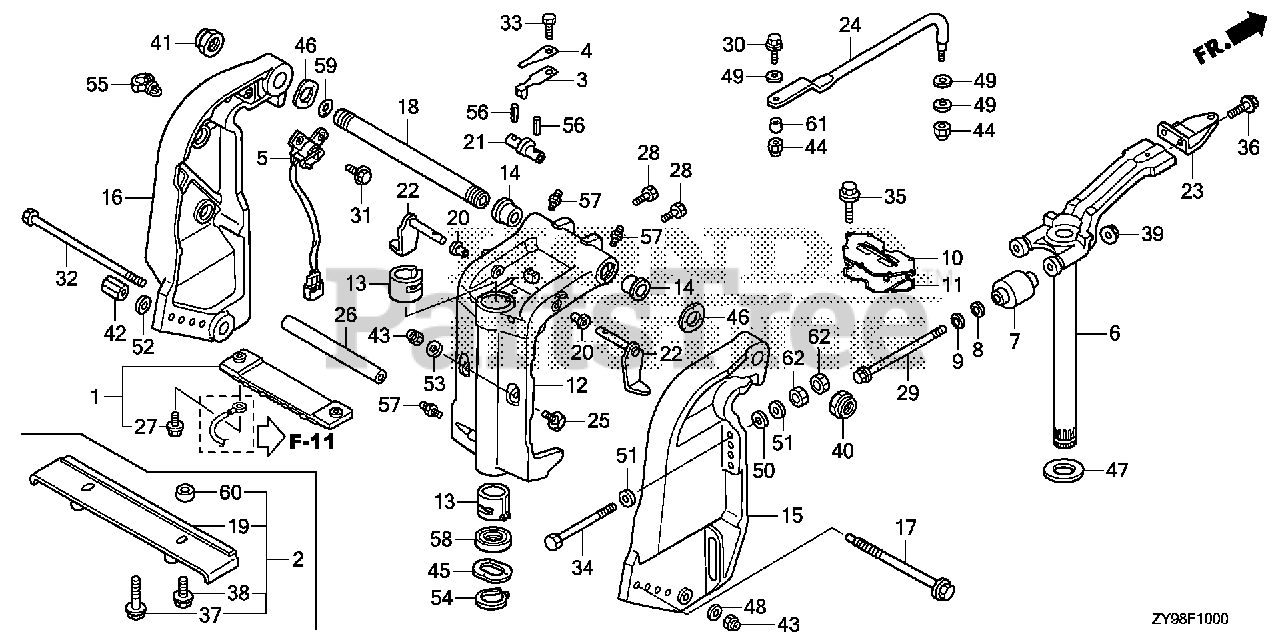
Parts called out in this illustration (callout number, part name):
1	METAL KIT, ANODE
2	PLATE KIT, SPLASH
3	SPRING, CLICK
4	SPRING, CLICK ASSIST
5	SENSOR ASSY., TRIM ANGLE
6	FRAME, MOUNTING
7	MOUNT, RUBBER (UPPER)
8	RUBBER, MOUNT STOPPER (UPPER)
9	STOPPER, MOUNT (UPPER)
10	COVER, MOUNT (UPPER)
11	SEAL, MOUNT COVER (UPPER)
12	CASE, SWIVEL *NHB14M* (AQUA MARINE SILVER METALLIC)
13	LINER, SWIVEL CASE
14	BUSH, SWIVEL CASE
15	BRACKET, R. STERN *NHB14M* (AQUA MARINE SILVER METALLIC)
16	BRACKET, L. STERN *NHB14M* (AQUA MARINE SILVER METALLIC)
17	ROD, ADJUSTING
18	SHAFT, TILTING
19	PLATE, SPLASH
20	BUSH, TILT ARM
21	BRACKET, TILTING
22	STOPPER, TILT
23	PLATE, STEERING
24	ROD, STEERING
25	RECEIVER, THRUST
26	COLLAR, CYLINDER (LOWER)
27	BOLT, FLANGE (6X23)
28	BOLT (1/4-28UNF)
29	BOLT, HEX. (12X186)
30	BOLT (3/8-24UNF)
31	BOLT, FLANGE (6X20)
32	BOLT, HEX. (10X235)
33	BOLT, HEX. (6X14)
34	BOLT, HEX. (12X119)
35	BOLT, FLANGE (8X25)
36	BOLT, FLANGE (10X25)
37	BOLT, FLANGE (6X25) (SUS-D)
38	BOLT, FLANGE (6X16) (SUS)
39	NUT, FLANGE (12MM)
40	NUT, SELF-LOCK (7/8-14UNF)
41	NUT, SELF-LOCK (25X2.0)
42	NUT, ADJUSTER ROD
43	NUT, FLANGE (10MM)
44	NUT, SELF-LOCK (3/8-24UNF)
45	WASHER, WAVE (40MM)
46	WASHER, WAVE (26MM)
47	WASHER, THRUST (34MM)
48	WASHER, PLAIN (10MM)
49	WASHER (10MM)
50	WASHER, PLAIN (12MM)
51	WASHER, PLAIN (12MM)
52	WASHER, PLAIN (12MM)
53	WASHER, PLAIN (10MM)
54	CIRCLIP (OUTER) (39MM)
55	CLIP, WIRE HARNESS
56	PIN, SPRING (2.5X20)
57	NIPPLE, GREASE
58	OIL SEAL (39.5X52X6) (ARAI)
59	O-RING (15.54X2.62)
60	COLLAR, SPLASH PLATE
61	COLLAR, STEERING ROD
62	NUT, HEX. (12MM)
